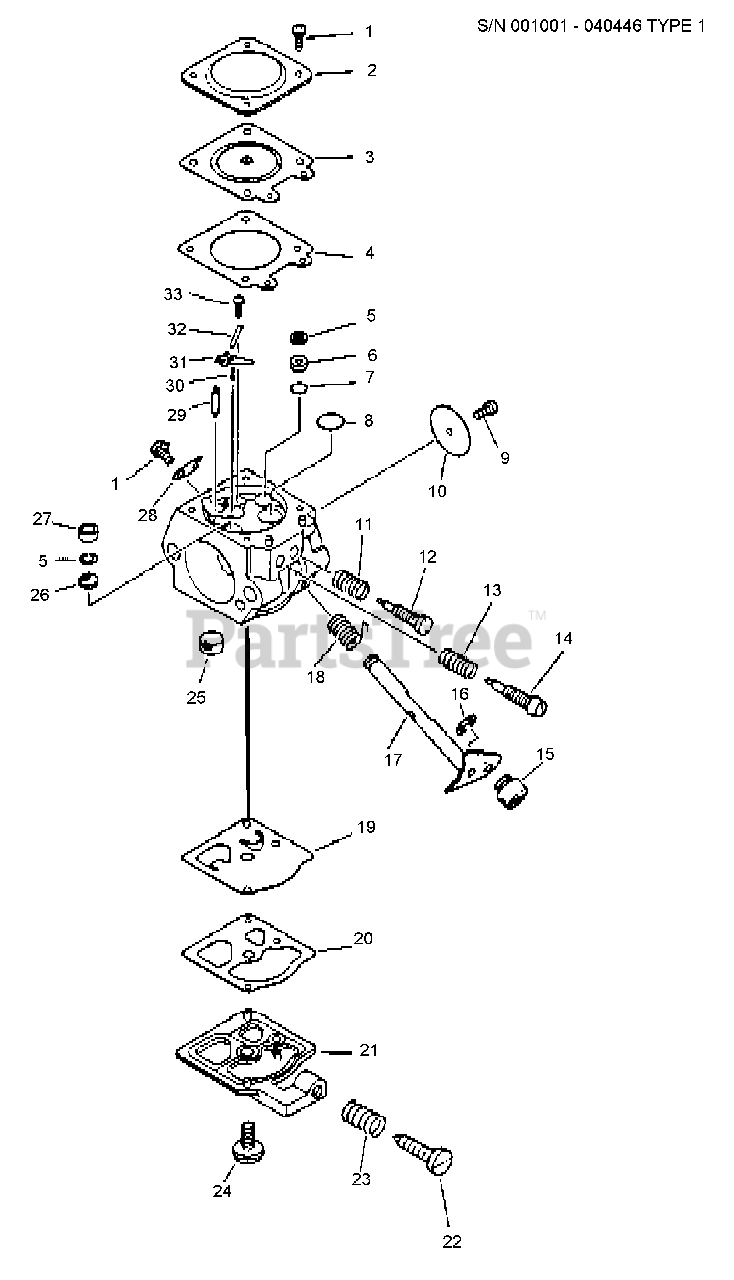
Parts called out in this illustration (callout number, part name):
1	SCREW
2	COVER, METERING
3	GASKET, PUMP
4	DIAPHRAGM, PUMP
5	RING, RETAINING
6	JET, MAIN
8	PLUG, WELCH
10	VALVE, THROTTLE
11	SPRING, NEEDLE ADJUST
12	NEEDLE - LOW SPEED
13	SPRING, NEEDLE ADJUST
14	NEEDLE - HIGH SPEED
16	RING, RETAINING
17	SHAFT, THROTTLE
18	SPRING, THROTTLE RETURN
19	GASKET, METERING
20	DIAPHRAGM, METERING
21	COVER, PUMP
22	SCREW, IDLE ADJUST
23	SPRING, IDLE ADJUST
24	SCREW, PUMP COVER
25	STRAINER
26	STRAINER
27	PLUG, WELCH
28	CLIP, THROTTLE SHAFT
29	VALVE, INLET NEEDLE
30	SPRING, METERING LEVER
31	LEVER, METERING
32	PIN, METERING LEVER
33	SCREW
